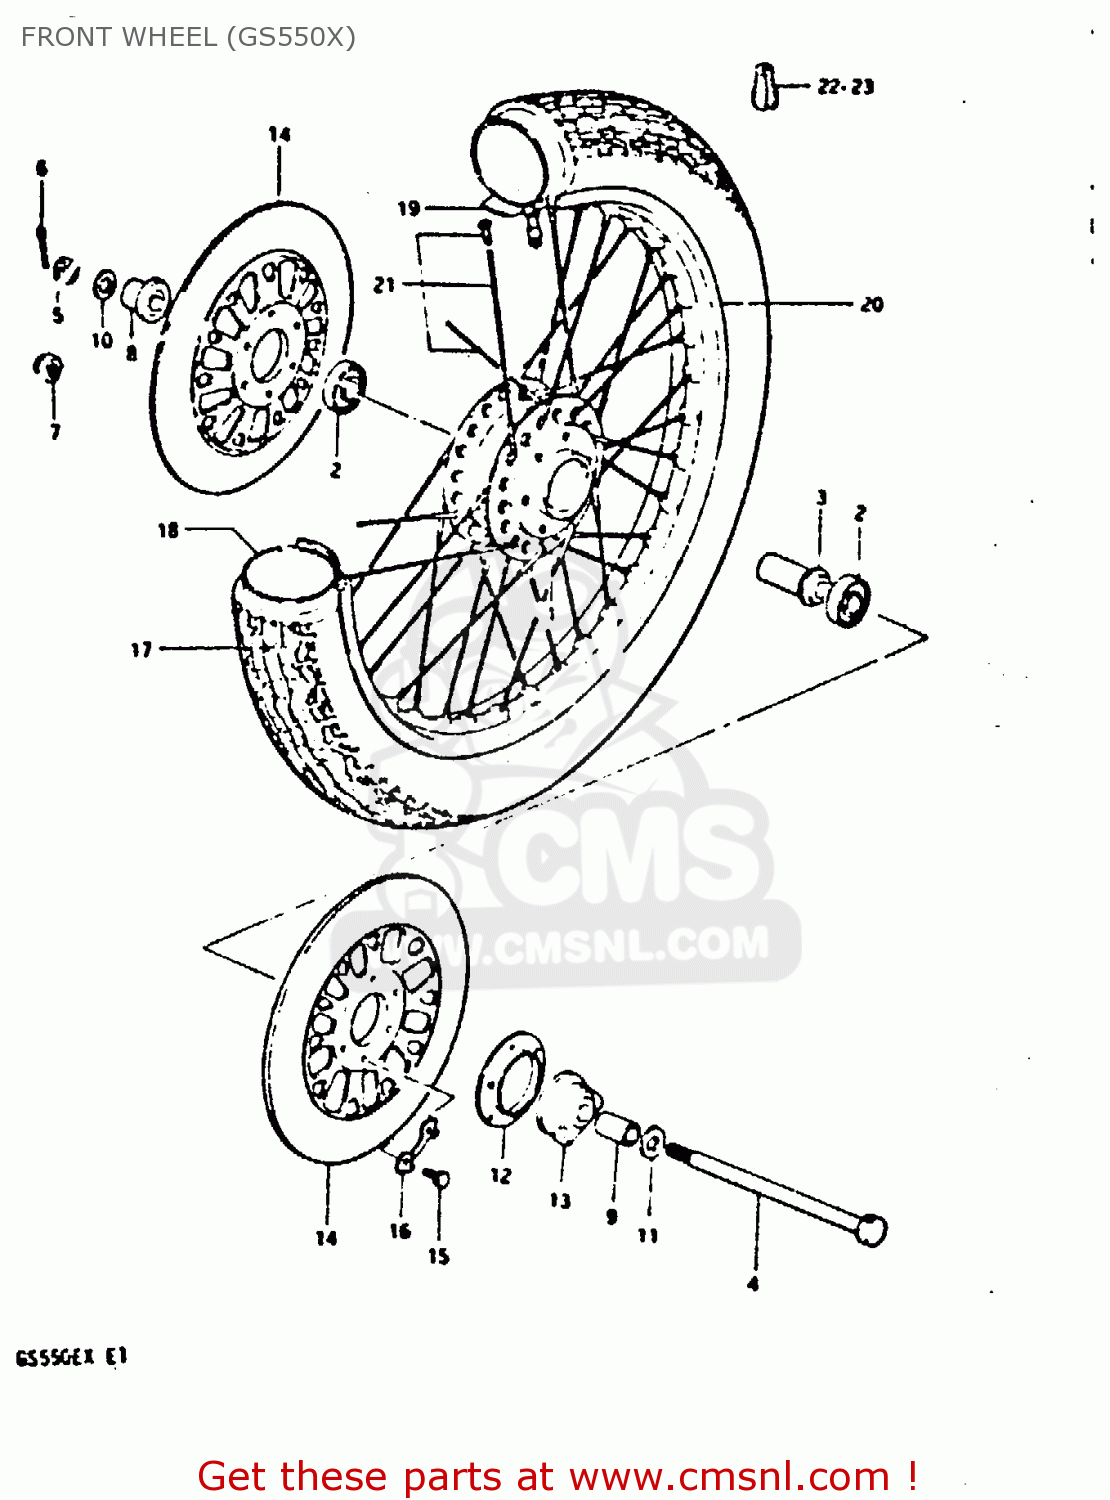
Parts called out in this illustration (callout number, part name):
1	DRUM,FRONT HUB
2	BEARING
3	SPACER,FR HUB BEARING
4	AXLE,FRONT
5	NUT 12MM
6	COTTER PIN
8	SPACER,FR HUB BEARING,R
9	SPACER(15X22X30)
10	WASHER
12	DUST SEAL,SPEEDOMETER GEAR BOX
13	BOX ASSEMBLY,SPEEDOMETER GEAR
14	DISC,FR BRAKE
15	BOLT(8X25)
16	WASHER
17	TIRE,FRONT
18	TUBE,INNER
19	PROTECTOR,WHL INR TUBE
20	RIM,FR WHEEL
21	SPOKE SET,FRONT
22	BALANCER,WHEEL (B)
23	BALANCER,WHEEL (30G)
